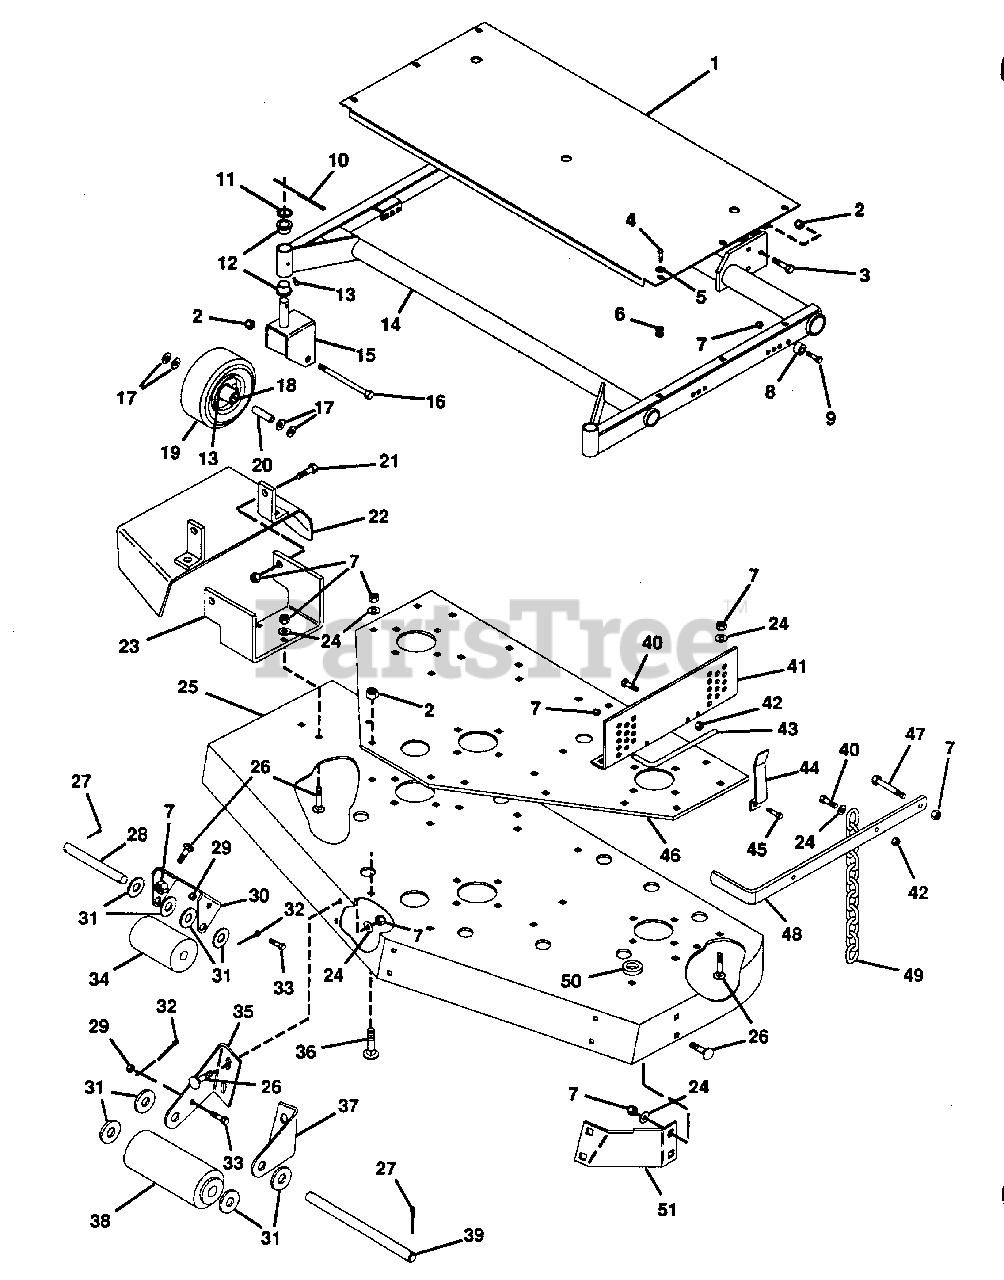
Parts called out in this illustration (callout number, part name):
1	GUARD, BELT 60" PM 18-H MOWER
2	NUT, LOCK 1/2-13
3	BOLT, HEX 1/2-13X1.50
4	SCREW, MACH. 1/4-20X.625 RD HD
5	WASHER, FLAT .281X.625X.065
6	GROMMET, PLASTIC
7	NUT, LOCK 3/8-16
8	BUSHING .391X.622X.670
9	BOLT, HEX 3/8-16X1.50
10	PIN, COTTER .187X1.62
11	RACE, BEARING THRUST
12	BUSHING, PIVOT
13	FITTING, LUBE 1/4-28
14	WELDMENT, MOWER FRAME
15	WELDMENT, CASTER FORK
16	BOLT, HEX 1/2-13X5.50
17	WASHER, FLAT .531 X 1.25 X .100
18	BEARING, GAUGE WHEEL
19	WHEEL, GAUGE
20	BUSHING, WHEEL .520X.750X3.312
21	BOLT, HEX 3/8-16X1.00
22	WELDMENT, DISCHARGE CHUTE
23	BRACKET, DISCHARGE CHUTE
24	WASHER, FLAT .406X.812X.065
25	WELDMENT, 60" MOWER
26	BOLT, 3/8-16X1.00 RD HD SQ NK
27	PIN, COTTER .25X1.0
28	ROD
29	NUT, HEX 1/4-20
30	BRACKET, ROLLER
31	WASHER, FLAT .656X1.312X.095
32	PIN, COTTER .25X2.0
33	BOLT, HEX 1/4-20X.75
34	ROLLER, GAGE
35	BRACKET, ROLLER R.H.
36	BOLT, 1/2-13X1.00 RD HD SQ NK
37	BRACKET, ROLLER L.H.
38	ROLLER, GAUGE
39	SHAFT, CENTER ROLLER
40	BOLT, HEX 5/16-18X1.00
41	BRACKET, MOWER SUPPORT L.H.
41	BRACKET, MOWER SUPPORT R.H.
42	NUT, LOCK 5/16-18
43	PIN, MOWER LOCKING
44	SPRING, PIN
45	BOLT, HEX 3/8-16X.75
46	PLATE, SUPPORT
47	BOLT, HEX 3/8-16X2.00
48	BAR, LIFT
49	CHAIN, HEIGHT ADJUSTMENT
50	SPACER, IDLER .406X.750X.188
51	BAFFLE, FRONT
NS	DECAL, DANGER HAND
NS	DECAL, DANGER FOOT
NS	DECAL, WARNING EYE
NS	STRIPE
NS	DECAL, LUBE
NS	DECAL, GRAVELY LOGO
